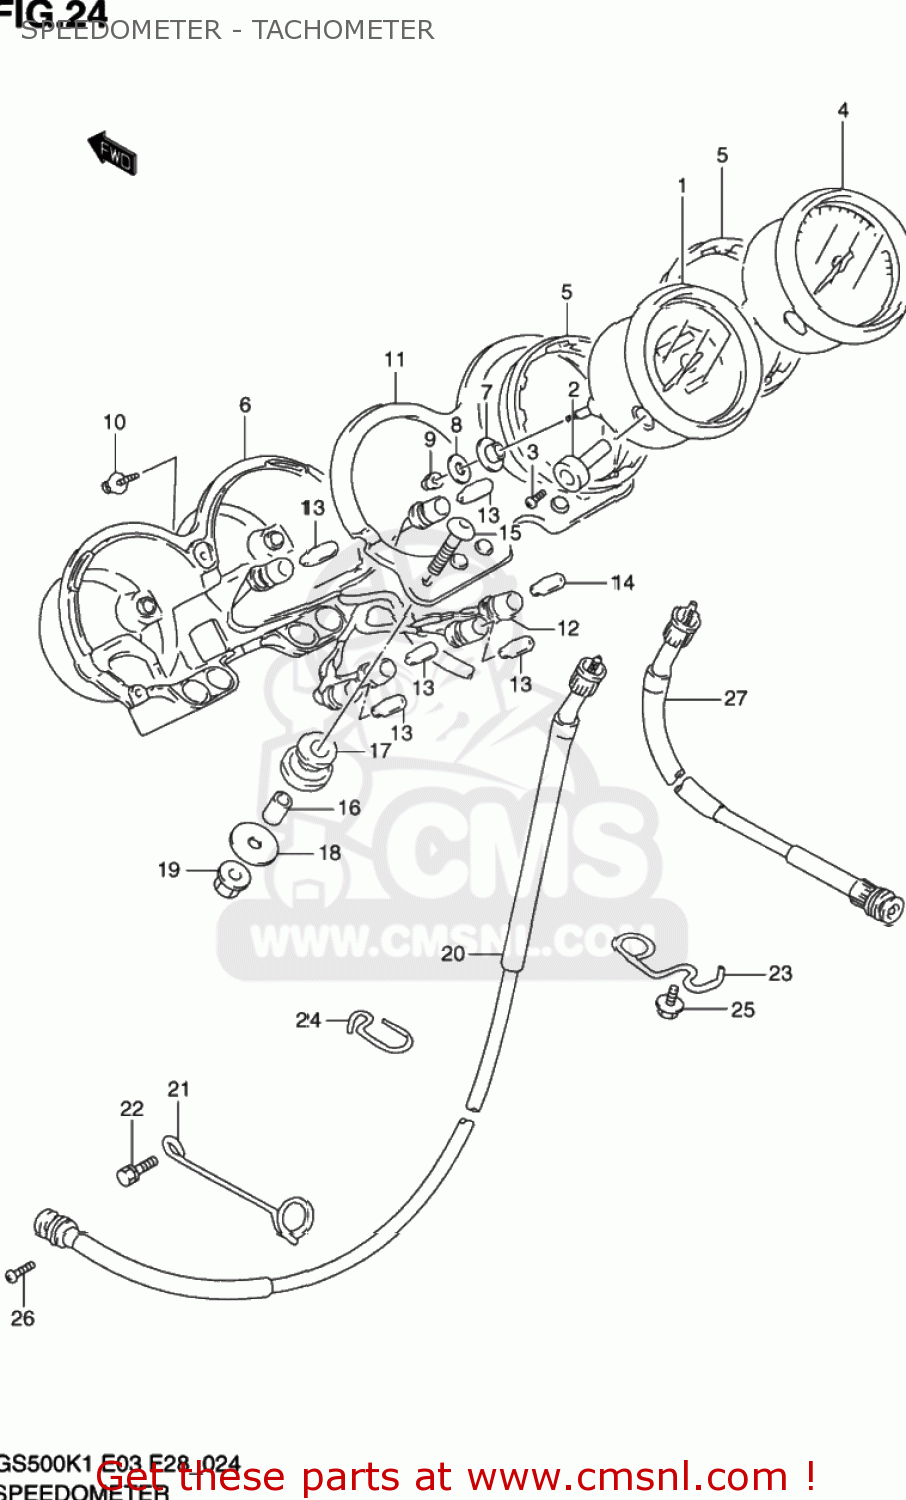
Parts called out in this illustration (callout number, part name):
1	SPEEDOMETER
2	KNOB,TRIP METER
3	SCREW(2X6)
4	TACHOMETER
5	DAMPER
6	COVER
7	CUSHION
8	WASHER(5.2X16X1)
9	NUT
10	SCREW
11	BRACKET,METER
12	SOCKET
13	BULB(12V3.4W,T10)
14	BULB(12V1.7W,T10)
15	BOLT(6X30)
16	SPACER(6.5X10X15.7)
17	CUSHION,METER BRACKET
18	WASHER(6.5X28X1.6)
19	NUT
20	CABLE ASSY,SPEEDOMETER
21	CLAMP,SPEEDOMETER CABLE
22	BOLT
23	GUIDE,SPEEDOMETER CABLE NO.2
24	GUIDE,SPEEDOMETER CABLE NO.3
25	BOLT
26	SCREW
27	CABLE ASSY,TACHOMETER
